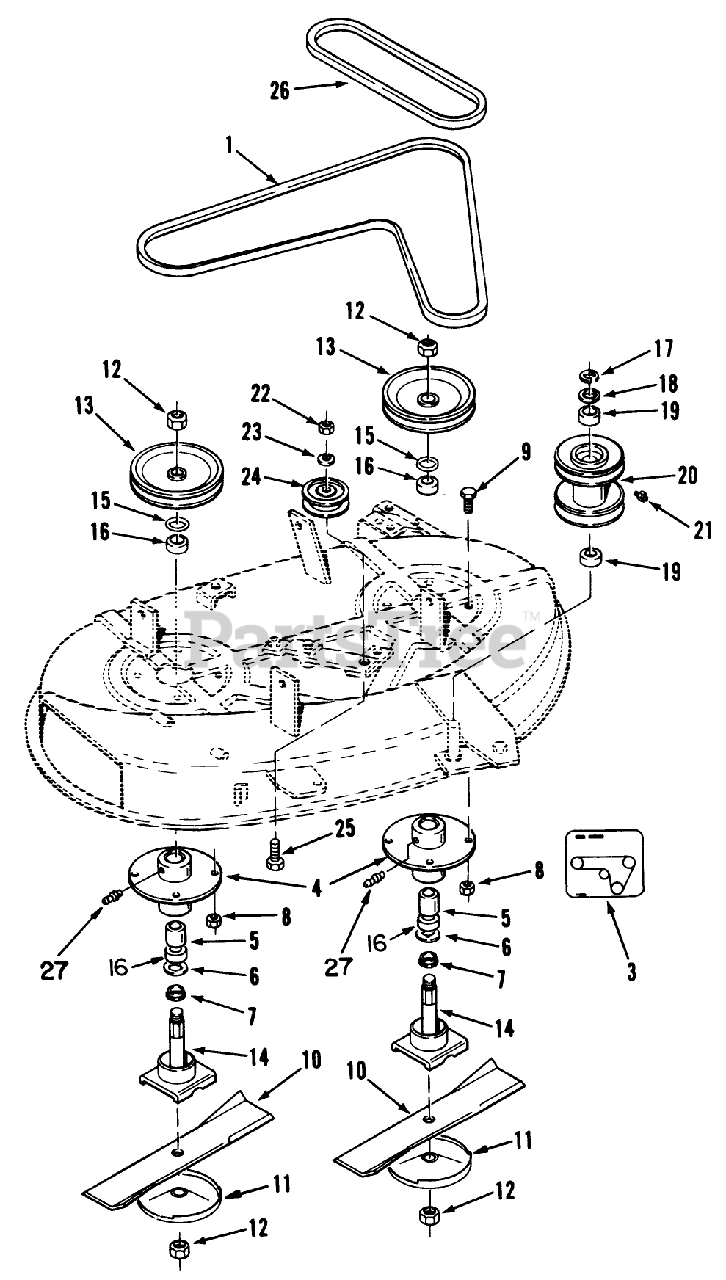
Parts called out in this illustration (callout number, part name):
1	V-BELT
3	Decal-Routing
4	Housing-Spindle
5	BEARING SPACER
6	RING-RETAINING
7	SPACER-SPINDLE
8	Nut
9	Bolt
10	Blade
11	Cup
12	NUT-LOCK NI
13	DECK PULLEY
14	SPINDLE SHAFT WA
15	Washer
16	BEARING-BALL
17	RETAINING RING
18	O RING
19	BEARING-BALL
20	PULLEY-COUNTER SHAFT
21	Zerk
22	NUT
23	Washer
24	Pulley
25	Bolt
26	V-BELT
27	Fitting-Grease
